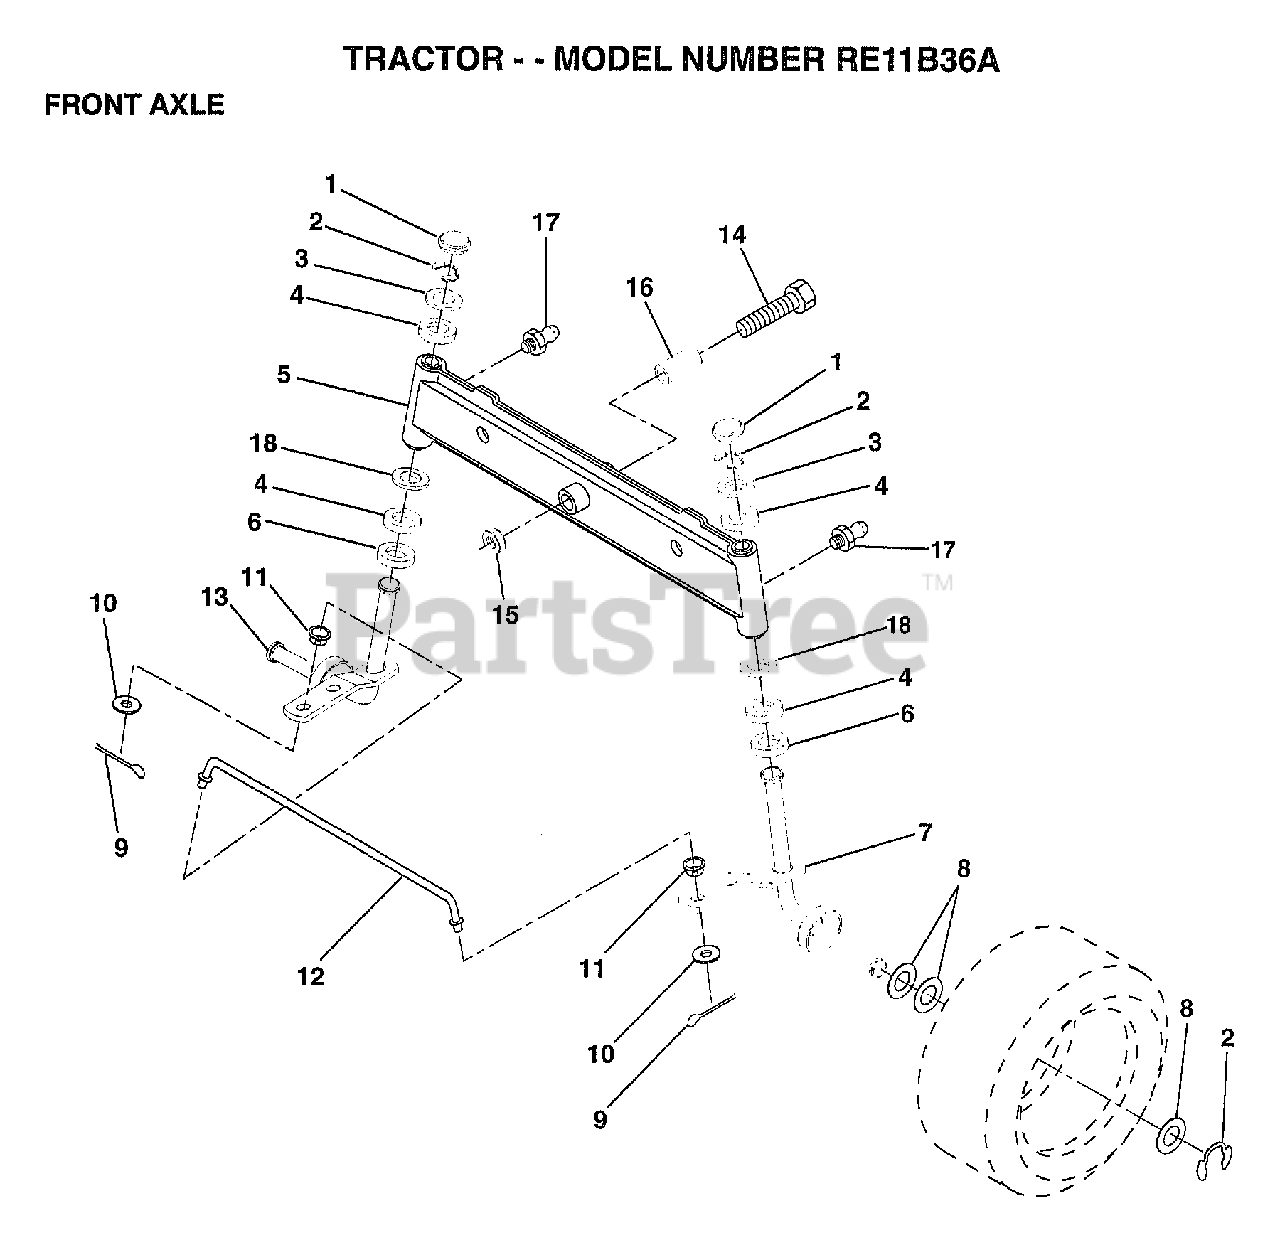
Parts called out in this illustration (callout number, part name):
1	CAP
2	RING
3	WASHER
4	COL. SRTG. BEAR.
5	AXLE ASM FRONT
6	WASHER .T
7	SPINDLE.ASSY.RH
8	WASHER
9	COTTER PIN
10	WASHER
11	BUSHING.DRAGLINK
12	TIE ROD
13	SPINDLE.ASSY.LH
14	BOLT HEX 5/8-11
15	"NUT-LOC,FLANGE LT"
16	BEARING
17	ZERK M
18	WASHER
